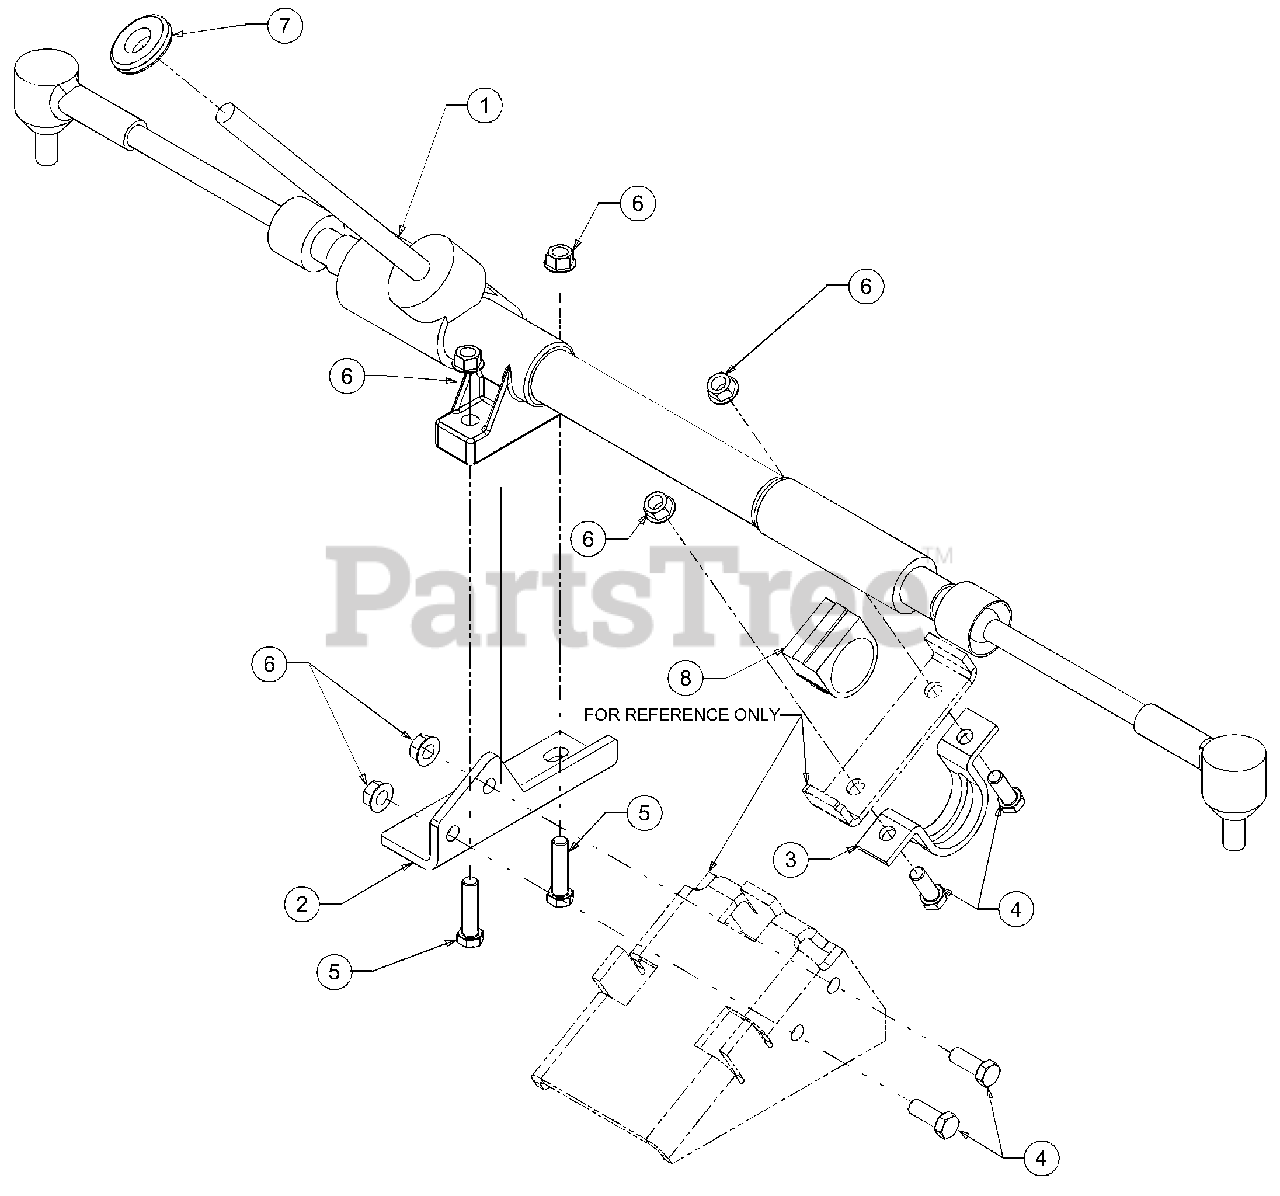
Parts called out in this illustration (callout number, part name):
1	Gear Assembly, Steering
4	Hex Screw, 3/8-16, 1.00, Gr5
5	Hex Screw, 3/8-16, 1.50, Gr5
6	Nut, Flange Lock, 3/8-16
7	Grommet, Steering Shaft
8	Bushing, Rubber
